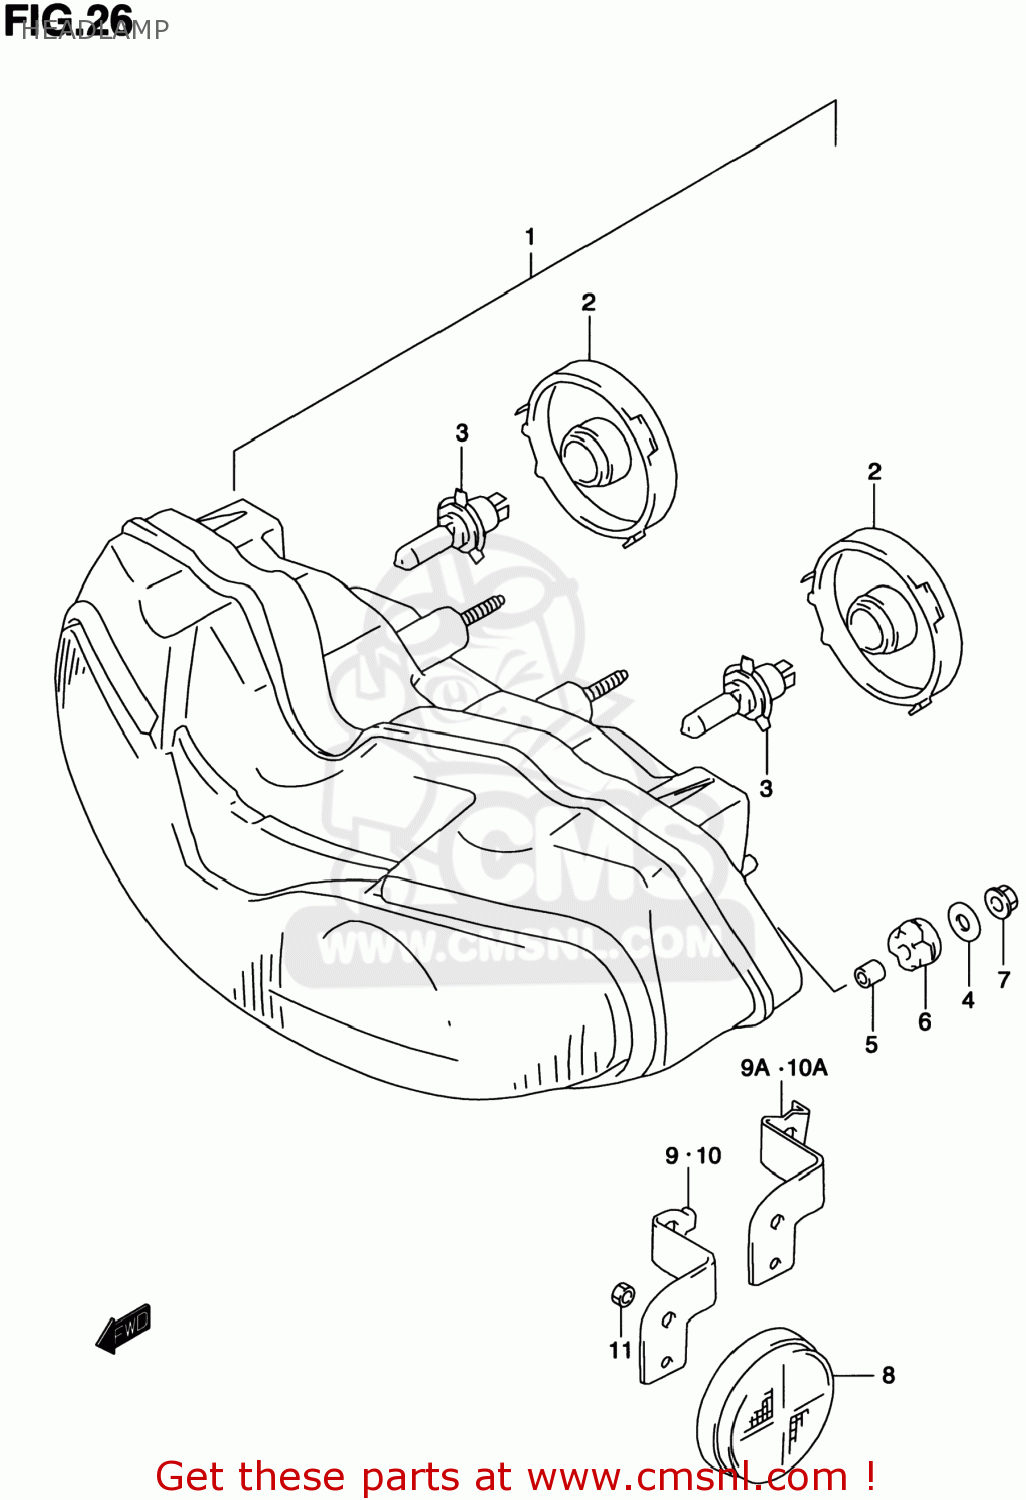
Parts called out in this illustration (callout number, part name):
1	HEADLAMP ASSY
2	COVER,SOCKET
3	BULB(12V60/55W,H4)
4	WASHER(6.5X20X1.6)
5	SPACER(6.5X9X12.5)
6	CUSHION
7	NUT
8	REFLECTOR,REFLEX FR
9	BRACKET,FR SIDE RR,R
9A	BRACKET,FR SIDE RR,R
10	BRACKET,FR SIDE RR,L
10A	BRACKET,FR SIDE RR,L
11	NUT
